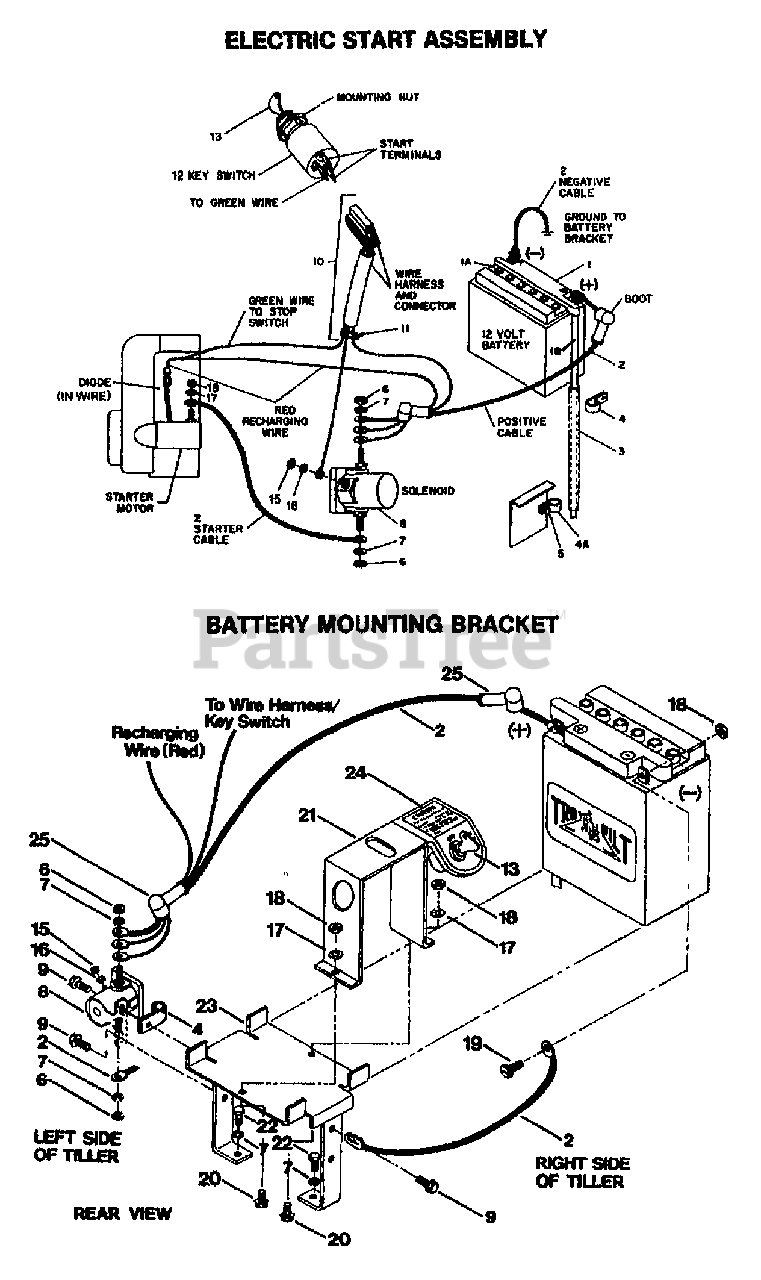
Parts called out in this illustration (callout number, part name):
1	BATTERY - 12 VOLT, 12 AMPHERE
1A	CAP-YELLOW
1A	CAP-BATTERY WHITE (PONY)
1B	TUBE-VENT BATTERY/HSE
2	CABLE-BATTERY
3	TUBING-RUBBER
4	CLAMP (SMALL)
4A	CLAMP (LARGE)
5	SCR-HHC 5/16-18X.75 GR 5 ZP
6	NUT-HEX 5/16-24
7	WASHER-LK .312 ZP
8	KIT-SOL W/HDW
9	SCR-HWH 1/4-20 X .5 STH
10	HARNESS-WIRE 6HP (AVAIL. AS COMPLETE UNIT ONLY)
11	TIE-TWIST LOCK
12	KEYSWITCH W/KEYS
13	KEYS(1 PAIR) FOR SWITCH
15	NUT-HH M10-32X.125
16	WASHER-EXTERNAL TOOTH 1
17	WASHER-LK .25 ZP
18	NUT-HEX 1/4-20 ZP
19	BOLT-SLHH 1/4-20 X .5 (REPLACEMENT HARDWARE FOR CABLE TO BATTERY CONNECTION)
20	SCR-CARR 1/4-20X1.25
21	PLTE-KEYSWITCH W/DEC-PONY 3 (INCL. #20418, DECAL)
22	SCR-HH 5/16-18X1.0 G5 ZP
23	BRKT-BATTERY PNT
24	DECAL-KEYSWITCH TILLER
